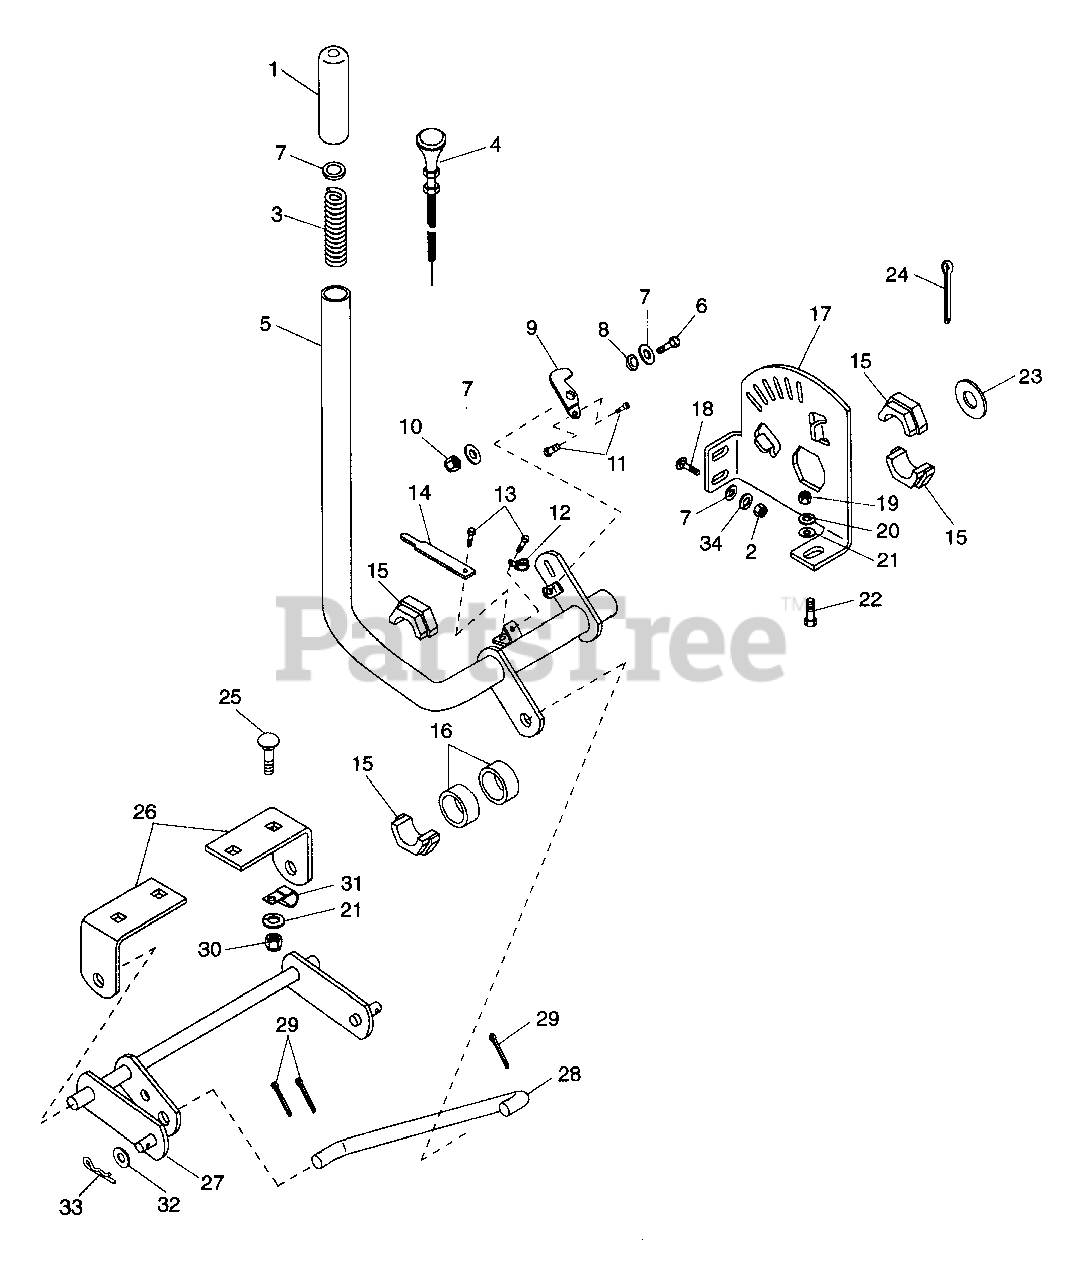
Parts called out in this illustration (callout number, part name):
1	HANDLE GRIP
2	NUT-HEX .312-18
3	SG-COMP .048X.59X2.06 WLD9
4	PUSH-PULL CONTROL
5	LIFT LEVER
6	BLT-HEX .31-18X.75 PL GR5
7	WSHR-FL-STL.312X.734X.065PL
8	SPACER BUSHING .5 X .32 X .21
10	NUT-LK .312-18 GR A PL
11	SWIVEL ASSY
12	CABLE CLAMP NON SKID
13	SCR-TAP 10-16X.50 HWH PL AB
14	INDICATOR
15	BSHG-FLG 1.014X1.750X.72
16	SPACER 1.070X1.380X.615
17	QUADRANT
18	BLT-RDHDSQNK.31-18X.88 GR5YWZC
19	NUT-LK-CTR .375-16 GR A PL
20	WSHR-FL-STL.406X.812X.065PL
21	WSHR-LK .375X.094 MED PL
22	BLT-HEX .38-16X1.00 PL
23	WSHR-FL-STL 1.016X1.625X.045
24	PIN-COTR .25X1.50 ST PL
25	BLT-RDHDSQSHNK .38-16X1.00 PL
26	CENTER LIFT BRACKET
27	LEVER - CENTER LIFT
28	LIFT LINK
29	PIN-COTR .12X1.0 PL
30	NUT-HEX .375-16
31	J-CLAMP
32	WSHR-FL-STL .630X1.005X.062 PL
33	PIN-HAIR EXT .12X.31X2.37 PL
34	WSHR-LK .312X.097 PL HVY
